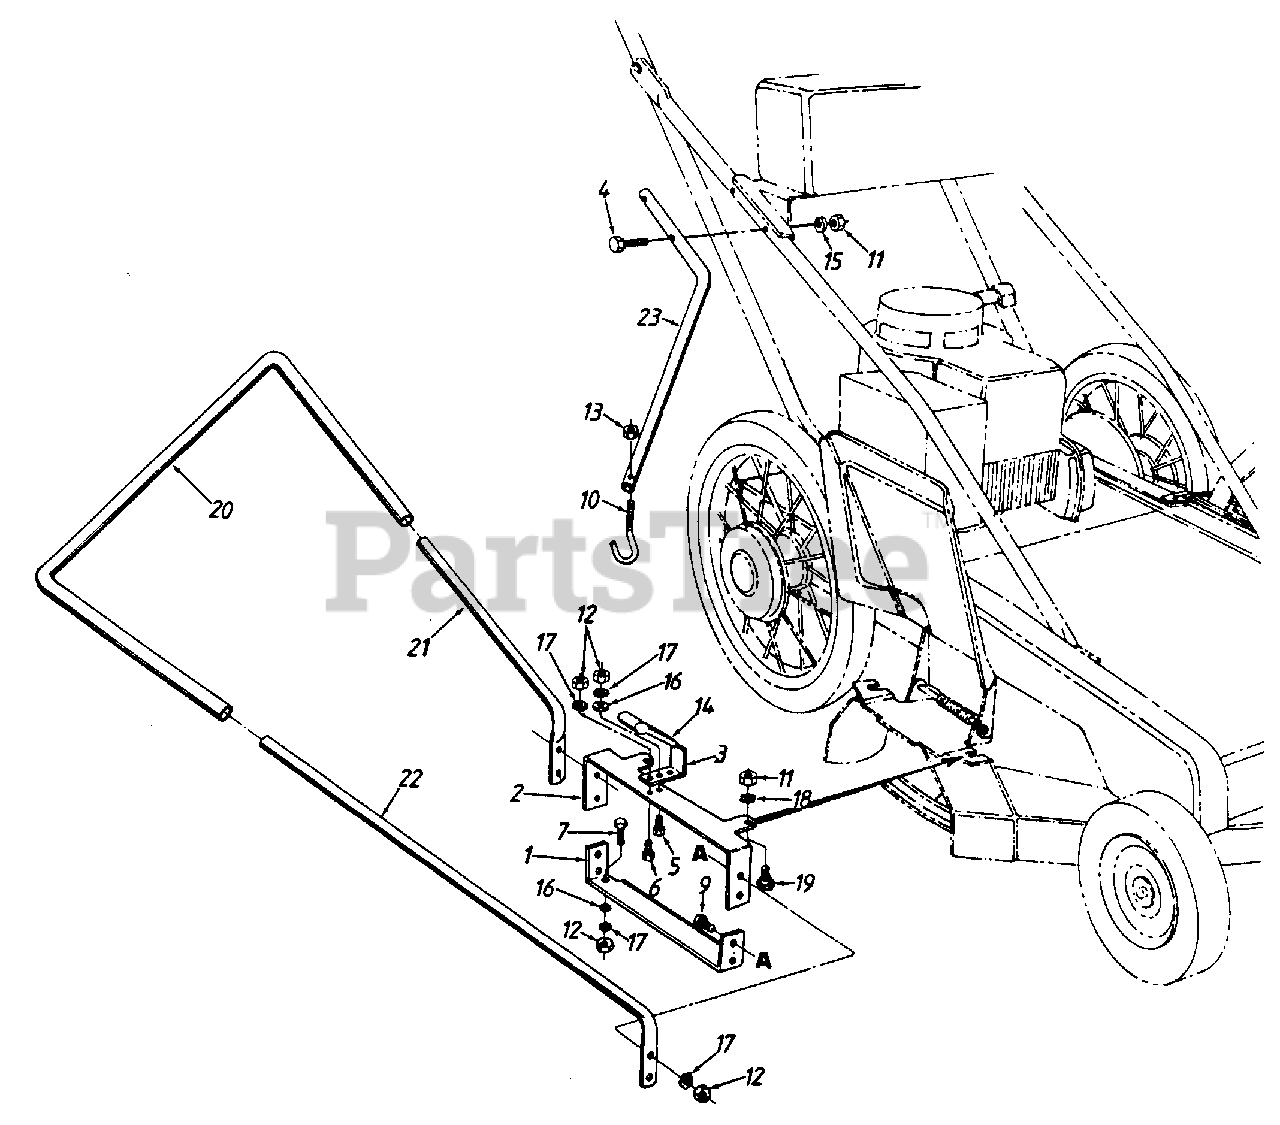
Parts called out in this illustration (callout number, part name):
1	SUPPORT-LOWER
2	SUPPORT-UPPER
3	BRACKET-HANDLE
4	SCREW-HEX 5/16-18 X 2.00
5	SCREW-HEX 1/4-20 X .75
6	SCREW-HEX 1/4-20 C .62
7	SCREW-HEX 1/4-20 X .50
9	SCREW-HEX 1/4-20 X 1.25
10	HOOK-CHAIN
11	NUT-HEX 5/16-18
12	NUT-HEX 1/4-20
13	NUT-INS LOCK 1/4-20
14	GRIP-FL BAR-END
15	WASHER-LOCK-5/16
16	WASHER-FL-.281 ID X .50 OD X .063
17	WASHER-EXTERN L 1/4
18	WASHER-EXTERN L 5/16
19	SCREW-SHLD .437 DIA X .350
20	FRAME-UPPER
21	FRAME-LOWER
22	FRAME-ARM-LOWER
23	ARM-HOLDING
